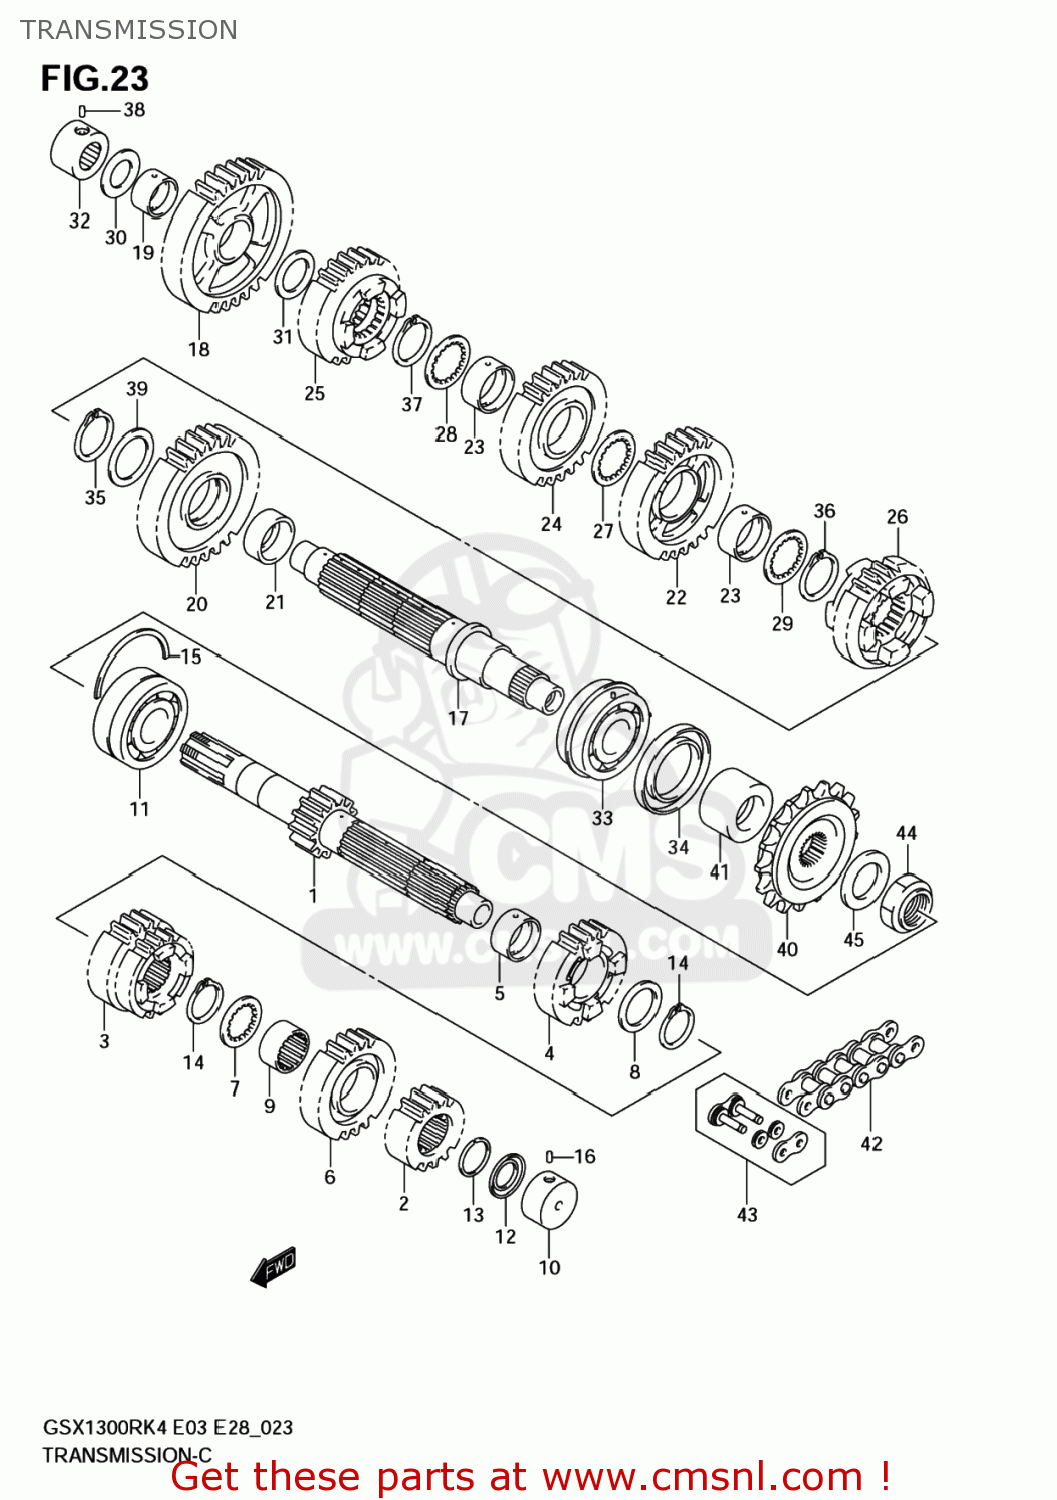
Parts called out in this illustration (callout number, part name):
1	SHAFT,COUNTER
2	GEAR,2ND DRIVE(NT:16)
3	GEAR,3RD & 4TH DRIVE(NT:19/21)
4	GEAR,5TH DRIVE(NT:22)
5	BUSH,5TH DRIVE GEAR
6	GEAR,6TH DRIVE
7	WASHER,LOCK
8	SHIM(27X36X2.5)
9	BUSH,6TH DRIVE GEAR
10	BEARING(20X34X17.5)
11	BEARING(25X62X25.4)
12	SEAL,OIL(20X31.2X2.7)
13	CIRCLIP
14	CIRCLIP
15	C RING
16	PIN
17	SHAFT,DRIVE
18	GEAR,1ST DRIVEN
19	BUSH,1ST DRIVEN GEAR
20	GEAR,2ND DRIVEN(NT:31)
21	BUSH,2ND DRIVEN GEAR
22	GEAR,3RD DRIVEN(NT:29)
23	BUSH,DRIVEN GEAR
24	GEAR,4TH DRIVEN(NT:27)
25	GEAR,5TH DRIVEN
26	GEAR,6TH DRIVEN
27	WASHER,LOCK
28	WASHER,LOCK
29	WASHER,LOCK
30	SHIM(20X34X1)
31	SHIM(24X34X1)
32	BEARING(20X34X20)
33	BEARING(30X62X23.8)
34	SEAL,OIL(42X62X7)
35	CIRCLIP
36	CIRCLIP
37	CIRCLIP
38	PIN
39	WASHER
40	SPROCKET,ENGINE(NT:17)
41	SPACER,ENGINE SPROCKET
42	CHAIN ASSEMBLY RKGB50GSVZ3
43	JOINT SET,DRIVE CHAIN
44	NUT
45	SHIM(25X40X1.5)
